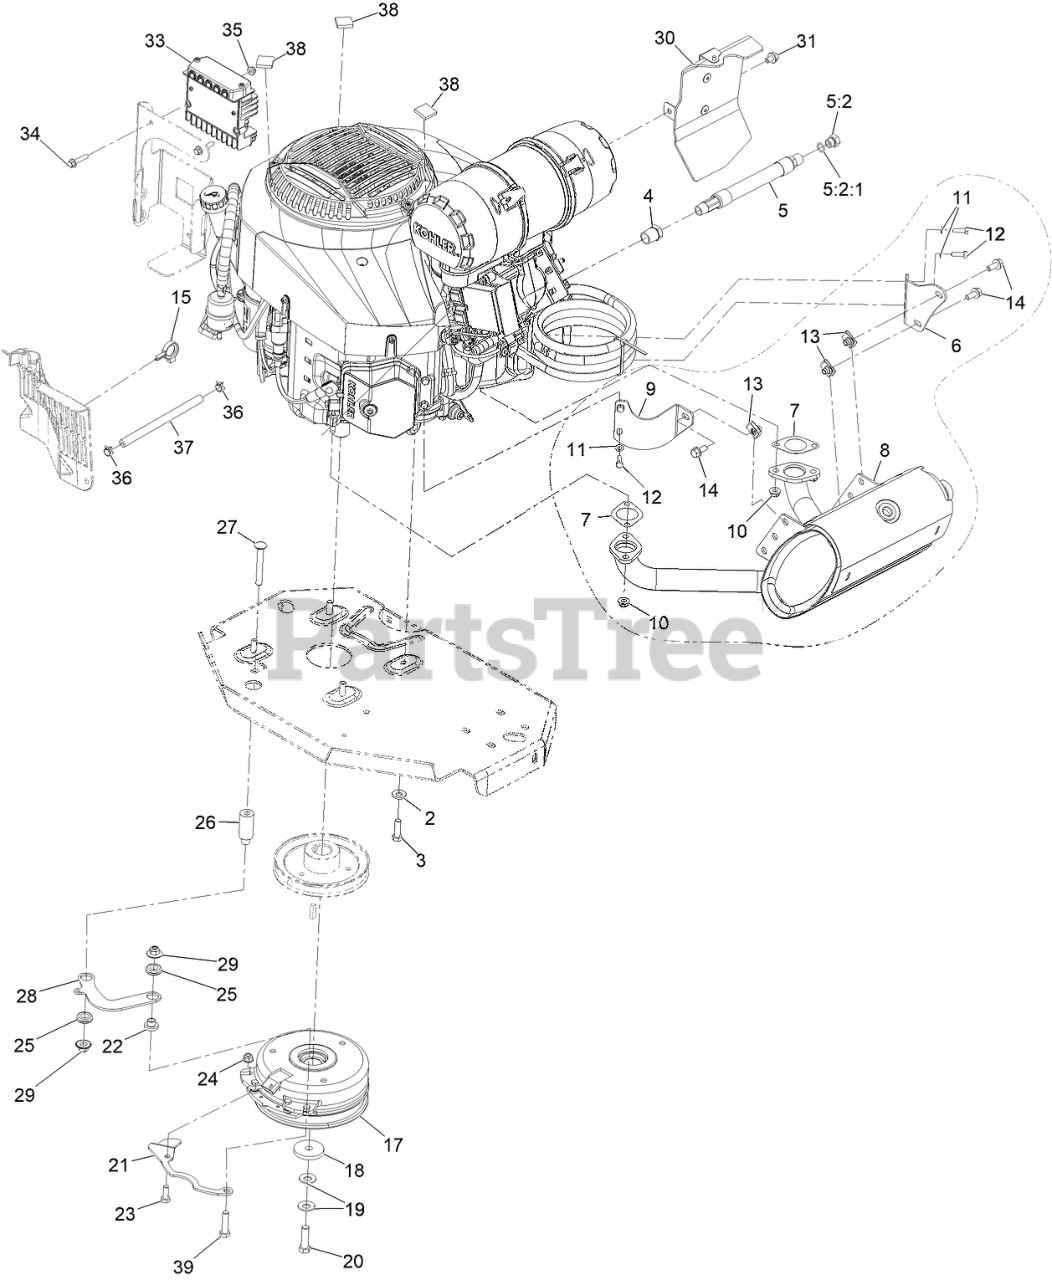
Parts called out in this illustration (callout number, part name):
2	WASHER-BELLEVILLE
3	SCREW-HH
4	BUSHING
5	Oil Drain Hose ASM
5:2	PLUG-HH
5:2:1	O-RING
6	BRACKET-MUFFLER
7	GASKET-EXHAUST
8	MUFFLER-940-980 KOH EFI
9	BRACKET-MUFFLER, FRONT
10	NUT-FLANGE, LOCK
11	WASHER-SPRING
12	SCREW-HH M6-1 X 20Mm W/Patch
14	SCREW-HHF
15	CLAMP-HOSE
17	CLUTCH KIT
18	WASHER-CLUTCH
19	WASHER-SPRING
20	SCREW-HH 7/16-20 X 1 1/2 W/LOCTITE
21	BELT-GUIDE
23	SCREW-HH
24	NUT-HF, NI
25	GROMMET-RUBBER
27	SCREW-CARR
28	LINK-ANCHOR, CLUTCH
29	Nut-Nyloc 3/8-16 Flg
30	Baffle ASM
31	Screw-HHF
33	Regulator And Rectifier ASM
34	SCREW-HHF
36	CLAMP-HOSE
37	HOSE-FUEL
39	SCREW-HH
